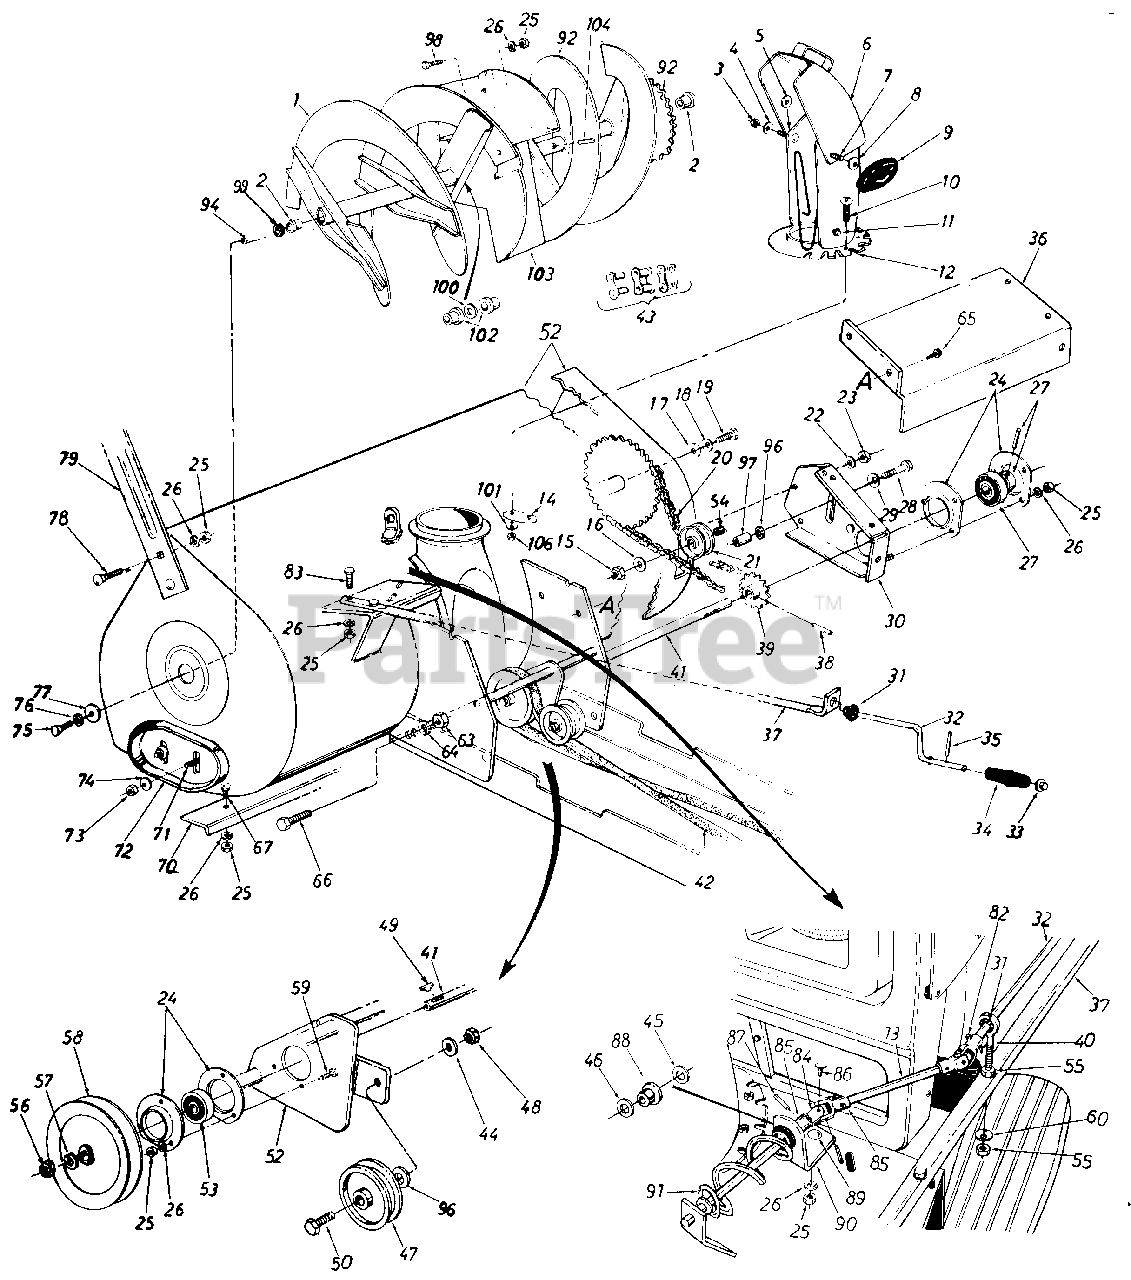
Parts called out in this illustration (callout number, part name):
3	Hex Cent. L.-Nut 5/16-18 Thd.
4	Belleville Wash. 3/8" I.D.
5	Flat Washer 3/8" I.D.
6	Top Chute Ass'y.
7	Carriage Bolt 5/16-18 x .62" Lg.*
8	Belleville Washs. 3/8" I.D.
9	Hand Knob
10	Truss Mach Scr 1/4-20 x .75" Lg.
11	Push Cap .188" Dia. Rod
12	Chute Ass'y.
13	Chute Crank Extension Rod
14	Chute Flange Keeper
15	L.-Nut 3/8-16 Thd.
16	Fl.-Wash.
17	Fl.-Wash.
18	Belleville Wash.
19	Hex Bolt 1/2-13 x 1.00" Lg.*
20	#420 Chain 1/2" Pitch x 77 Links
21	Plastic Idler 2.00" O.D.
22	L.-Wash. 1/4" I.D.*
23	Hex Nut 1/4-20 Thd.*
24	Bearing Housing
25	Hex Nut 5/16-18 Thd.*
26	L.-Wash. 5/16" I.D.*
27	Self-Aligning Bearing
28	Hex Bolt 3/8-16 x 1.75" L*
29	Belleville Wash. 3/8" I.D.
30	Chain Guard Ass'y.
31	Nylon Bushing
32	Chute Crank .375 Dia. x 33" Lg.
33	Push Nut 3/8" Rod
34	Knob (Black)
35	Roll Pin
36	Drive Shaft Cover
39	14 Teeth Sprocket Ass'y.
40	Eyebolt 5/16-18 x 3.0" Lg.
41	Drive Shaft
42	"V"Belt 1/2" x 88" Lg. Kevlar
43	Master Link for #420 Chain
44	L.-Wash. 3/8" I.D.*
45	Fl.-Wash. .385 I.D. x .62" O.D.
46	Fl.-Wash. .390 I.D. x 1.50" O.D.
47	Fl.-Idler with Flanges
48	Hex Jam L.-Nut 3/8-26 Thd.
49	#61 Hi-Pro Key
50	Hex Bolt 3/8-16 x 1.50" Lg.*
52	Spiral Housing Ass'y.
53	Self-Aligning Bearing
54	Sleeve Bearing .50" I.D.
55	Hex Nut 5/16-18 Thd.*
56	Hex Nut 3/4-10 Thd.
57	L.-Wash. 3/4" I.D.
58	"V"Pulley .750" I.D. x 6.00" O.D.
59	Hex Sems Bolt 5/16-18 x .75" Lg.*
60	Bell.-Wash. .345" I.D. x .88" O.D.
63	Hex L.-Nut 1/2-20 Thd.
64	L.-Wash. 1/2"1.D.*
65	Hex Wash. Hd. Tap Scr. 1/4-20 x .50" Lg.
66	Hex Bolt 1/2-20 x 1.25" Lg.*
67	Carriage Bolt 5/16-18 x .62"*
72	Skid Shoe
73	Hex Nut 3/8-16 Thd.*
74	Belleville Wash. 3/8" I.D.
75	Hex Bolt 1/2-13 x 1.00" Lg.*
76	Belleville Wash. 1/2" I.D.
77	Fl.-Wash.
78	Carriage Bolt 5/16-18 x .62" Lg.*
79	Drift Cutter
82	Cotter Pin
83	Hex Bolt 5/16-18 x 1.50" Lg.*
84	Joint Block
85	Joint Bracket Ass'y.
86	Oval Head Rivet
87	Spring Pin Roll 118" Dia. x .75" Lg.*
88	Nylon Bushing
89	Carriage Bolt 5/16-18 x .62
90	Chute Crank Bracket
91	Chute Crank Ass'y.
96	Flat Washer
97	Idler Spacer
98	Carriage Bolt 5/16-18 x .75" Lg.
99	Fl.-Wash. 1.0" I.D. x 1.75" O.D.
100	Fl.-Wash. 1.03" I.D. x 1.62" O.D.
101	Bell. Wash. 1/4" I.D.
102	Plastic Bushing
106	Hex Nut 1/4-20 Thd.
